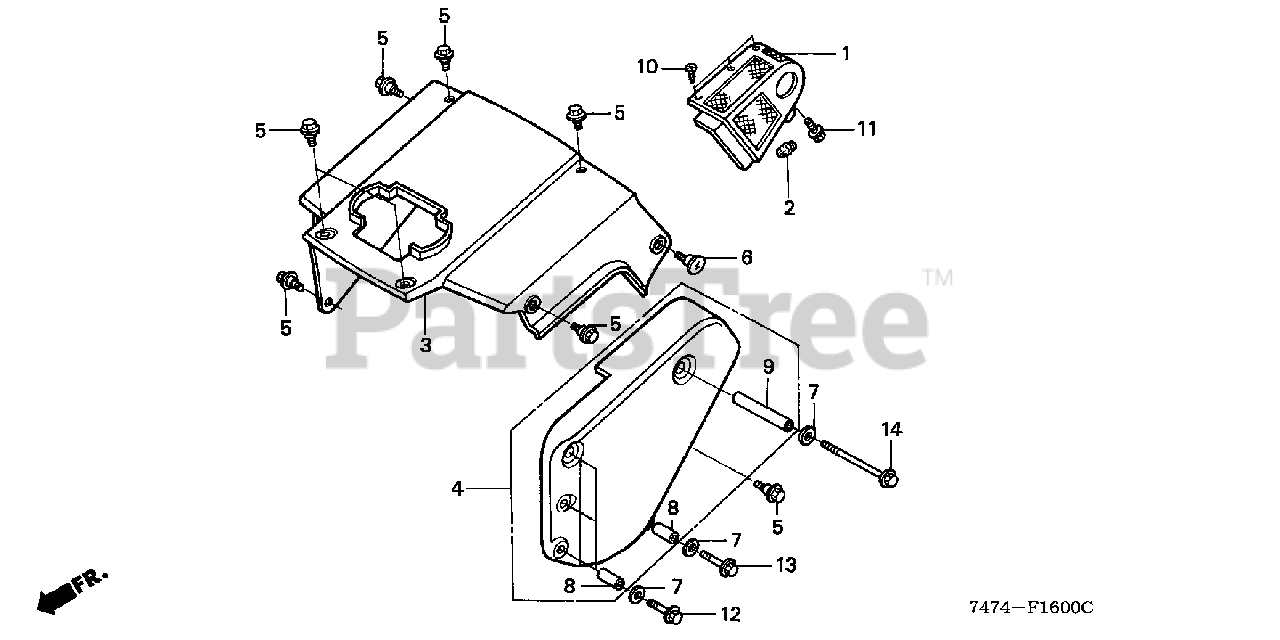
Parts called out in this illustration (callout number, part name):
1	PROTECTOR, MUFFLER *NH105* (MAT BLACK)
3	COVER, FR. *R8* (BRIGHT RED)
4	COVER, BELT *R280* (POWER RED)
5	BOLT, FLANGE (6MM) (BLACK)
6	SCREW, METER VISOR SETTING
7	WASHER (6MM)
8	COLLAR A, BELT COVER
9	COLLAR B, BELT COVER
10	SCREW, TAPPING (5X10)
11	BOLT, FLANGE (6X16)
12	BOLT, FLANGE (6X32)
13	BOLT, FLANGE (6X35)
14	BOLT, FLANGE (6X85)
